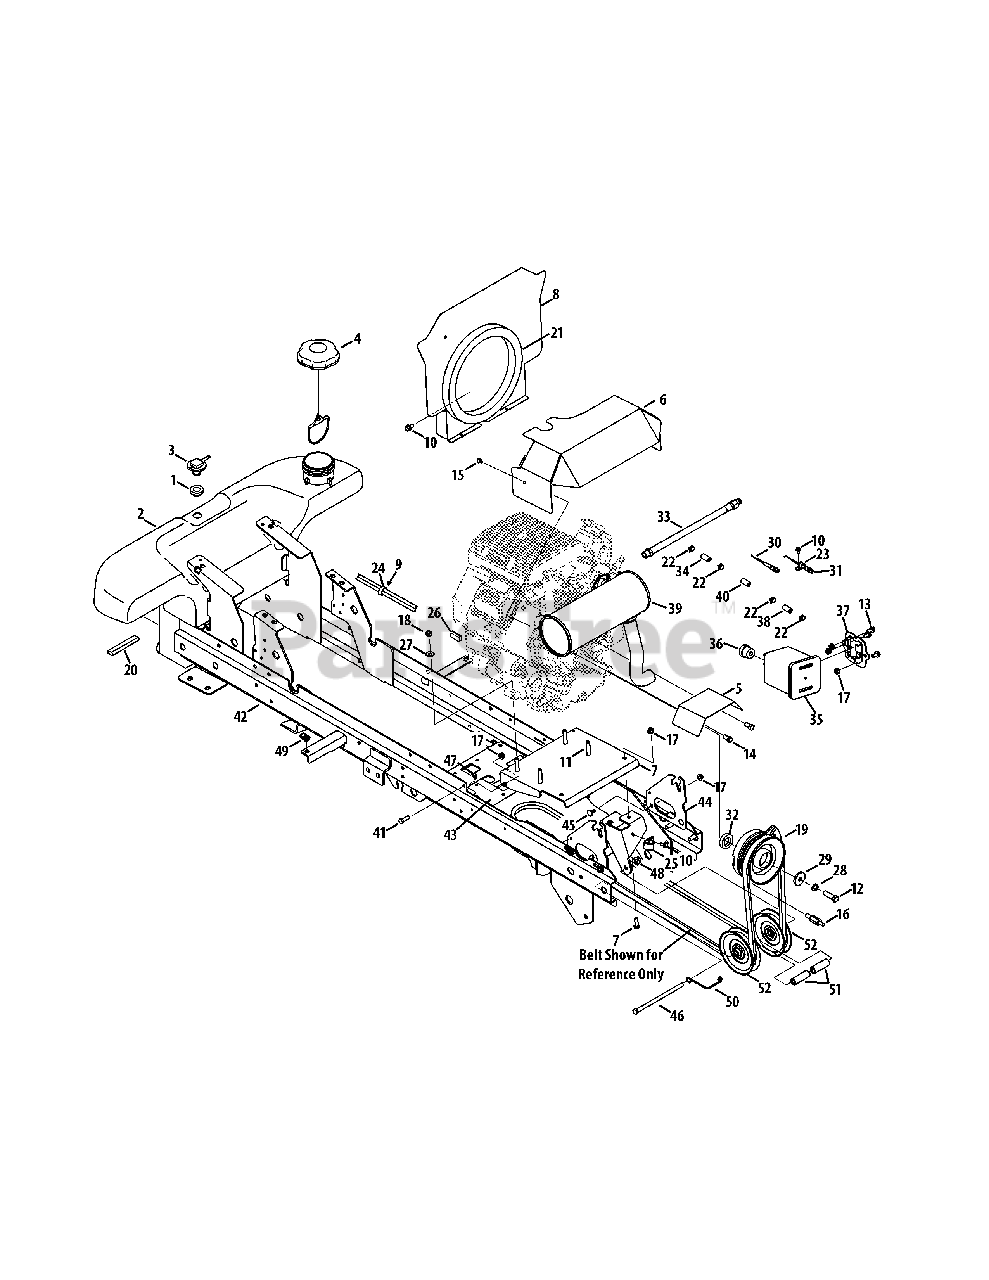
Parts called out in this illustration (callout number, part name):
1	Rubber Grommet, 23.0 x 3.55
2	Fuel Tank
3	Fuel Rollover Valve
4	Fuel Cap, 3.50
5	Clutch Heat Shield
6	Engine Upper Shield
7	Engine Mount Bracket
8	Engine Baffle Plate
9	AB Screw, #10-16 x .500
10	Hex Washer Screw, 5/16-18 x .750
11	Hex Screw, 3/8-24 x 1.75
12	Hex Screw, 7/16-20 x 1.50
13	Hex Screw, 5/16-180 x 1.50
14	Hex Screw, 3/8-16 x .750
15	Hex Screw, M6-1.0 x 10
16	Clutch Stop Stud
17	Flange Lock Nut, 5/16-18
18	Hex Lock Nut, 3/8-24
19	Clutch (GT Models)
19	Clutch (GTX Models)
20	Tape Foam, .75 x .25
21	Intake Gasket Foam
22	Hose Clamp
23	Clamp, 9/16
24	Hose Clamp, 1.0
25	Clamp, 1.0
27	Spring Washer, .401 x .870 x .060
28	Lock Washer, 7/16
29	Flat Washer, .45 x 1.5 x .172
30	Choke Control Cable
31	Throttle Control Cable
32	PTO Spcr., 1.00 x 1.62 x .4 (GT Models)
32	PTO Spcr., 1.13 x 1.62 x .21 (GTX Models)
33	Oil Drain Hose
34	Low Permeation Fuel Hose
35	Carbon Canister
36	Canister Vent Filter
37	Canister Adapter Bracket
38	Low Permeation Fuel Hose
39	Twin Muffler
41	Hex Screw, 5/16-18 x 1.00
42	Frame (GT Models)
42	Frame (GTX Models)
44	Hood Tilt Bracket
45	Carriage Bolt, 5/16-18 x .750
46	Hex Screw, 3/8-16 x 7.25
47	Hex Washer Screw, 1/4-20 x .500
48	Flange Lock Nut, 3/8-16
49	U-Nut, 5/16-18
50	Belt Guide
51	Idler Spacer, .41 x .875 x 2.19
52	Idler Pulley
